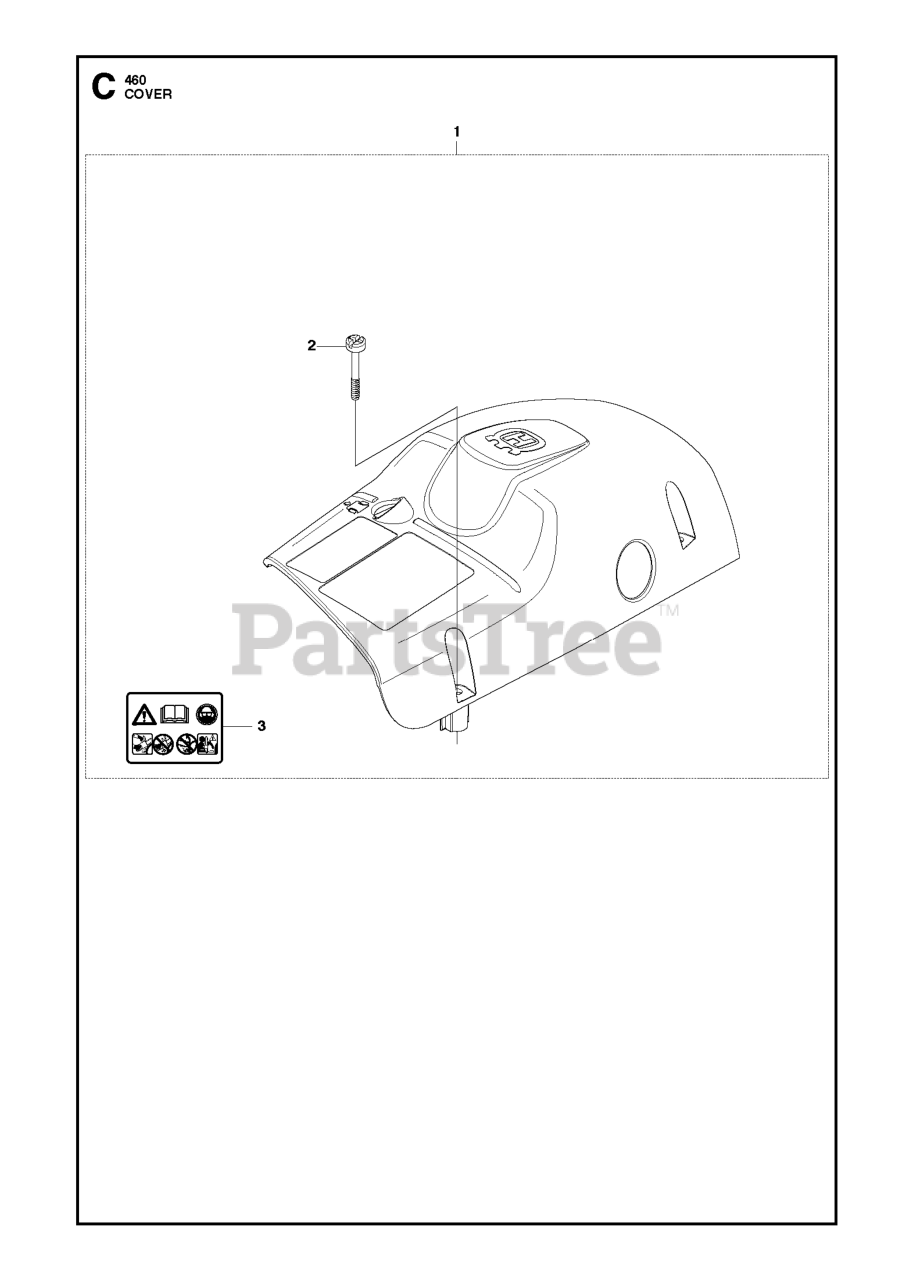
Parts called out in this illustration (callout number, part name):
1	SUBASM.SHAFT.BRAKE.WLDMNT.MED
1	CYLINDER COVER
2	DECK.LIFT.PNT.WELDMENT.RZ.BLK
3	ROD, HANDLE RELEASE
4	RB ROD, LATCH RELEASE
5	SPRING, COMPRESSION
7	E-RING 5/8
8	GRIP, HANDLE, BLACK 4"
9	BUTTON, PUSH, BLACK
10	LINK, REAR SUSPENSION
11	ASSEMBLY, BRKT LINK
12	ARM.SUSPENSION.MOWER
13	SB 3/8-16 X 3/8 SKT HD ZD
14	NUT HEX 3/8-16 NYLON, THIN
15	PLASTIC NUT
16	LOCKNUT.NYLOC.1/4-20
17	NUT, LIFT LINK 7/16-20
